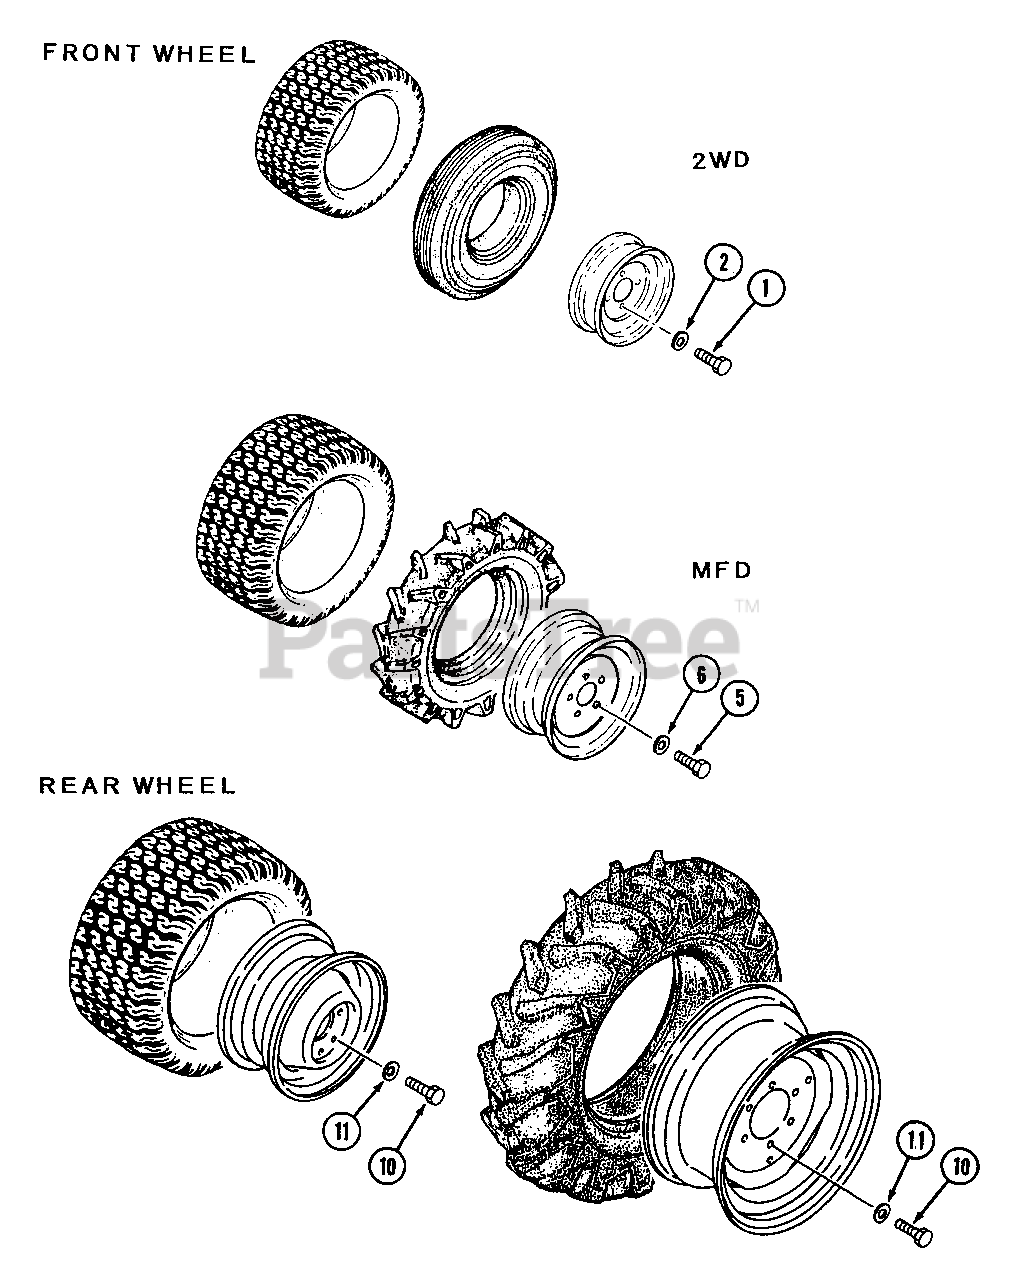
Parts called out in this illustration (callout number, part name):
1	Bolt
5	Bolt
6	Washer
10	Bolt
